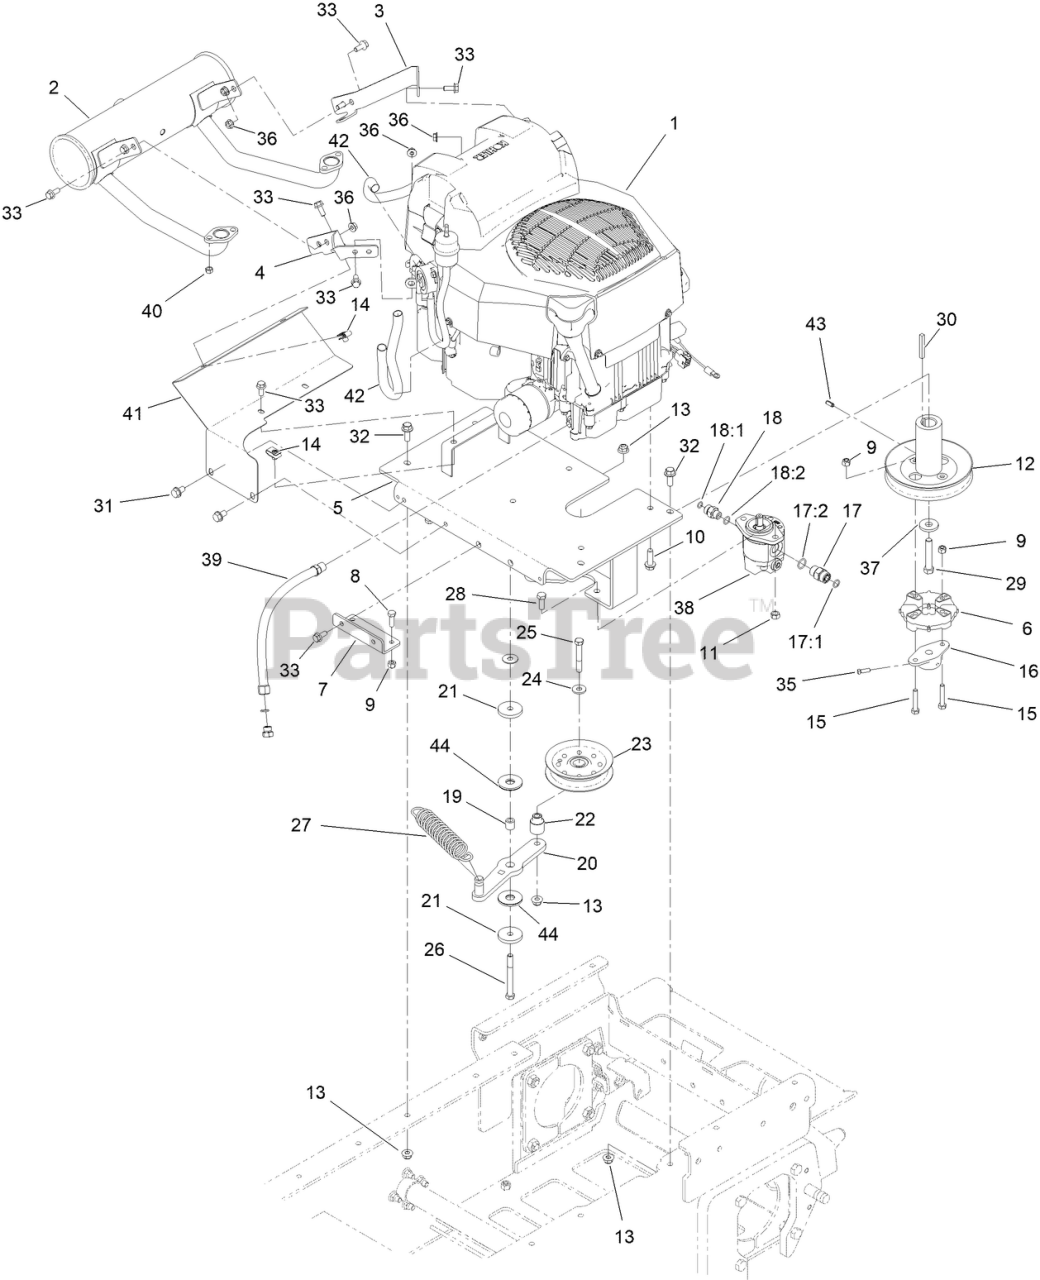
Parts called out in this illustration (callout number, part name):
1	ENGINE-KOHLER, ZT740 [SERVICE]
2	MUFFLER-KOHLER
3	BRACKET-MUFFLER
4	BRACKET-MUFFLER
5	ENGINE PLATE ASM (WELDED)
6	COUPLER-RUBBER
7	BRACKET-TANK, HYDRO
8	SCREW-HH
9	NUT-LOCK, NI
10	SCREW-THD
11	NUT-HEX
12	PULLEY-ENGINE
13	NUT-HF, NI
14	NUT-CLIP, U
15	SCREW-HH
16	HUB-PUMP
17	FITTING-STRAIGHT
17:1	O-RING
17:2	O-RING
18	FITTING-STRAIGHT
18:1	O-RING
18:2	O-RING
19	SPACER-KNOB, SEAT
20	IDLER ARM ASM (WELDED)
21	WASHER-PLAIN
22	BUSHING-IDLER
24	WASHER-HARDENED
25	SCREW-HH
26	SCREW-HH
27	SPRING-EXTENSION
28	SCREW-HH
29	SCREW-HH
31	SCREW-HHFTF
32	SCREW-HHF
33	SCREW-HHF
35	SCREW-SQH
36	NUT-FLANGE
37	WASHER-FLAT
38	PUMP-GEAR
39	HOSE-DRAIN, OIL
41	SHIELD-MANIFOLD
42	SLEEVE-THERMAL
43	PIN-ROLL
44	WASHER-FRICTION, COMPOSITE
